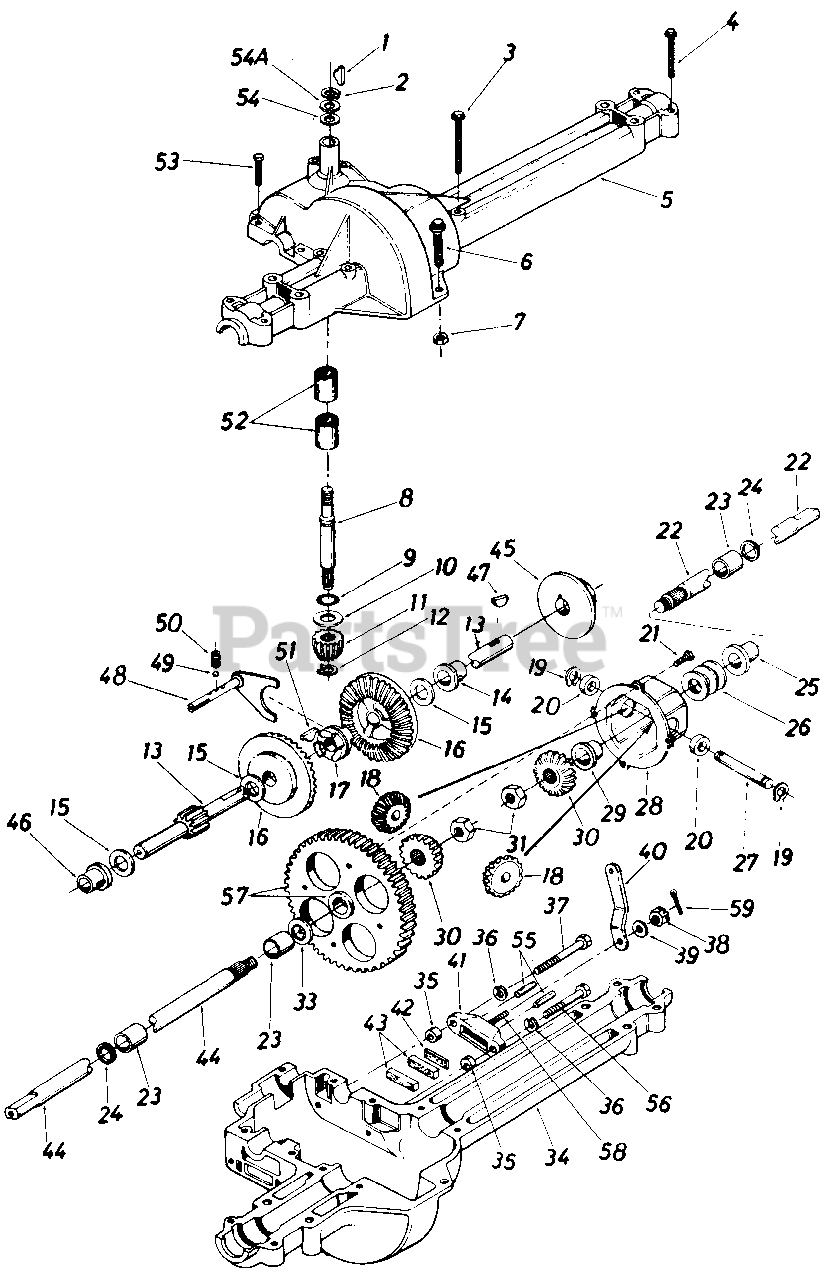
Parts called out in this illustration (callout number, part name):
1	#4 Hi-Pro Key 3/32 x 5/8" Dia.
2	Snap Ring .625" Shaft
3	Hex Bolt 1/4-20 x 1.75" Lg.
4	Hex Bolt 1/4-20 x 1.25" Lg.
5	Upper Housing
6	Hex Fl-Bolt 1/4-20 x .75" Lg.
7	Hex Nut 1/4-20 Thd.
8	Input Shaft
9	Square Seal 5/8" I.D.
10	Thrust Washer 5/8" I.D. x 1.25" O.D.
11	Pinion Input 14T
12	Retaining Ring 7/16" Ext.
13	Drive Shaft R.H.
14	Flange Brg. 5/8" I.D. x 3/4" Lg.
15	Fl-Wash.
16	Bevel Gear 42T
17	Clutch Collar
18	Miter Gear 15T
19	Snap Ring
20	Thrust Bearing 1/2" I.D. x 1.0" O.D.
21	Pan Head Scr. 1/4-20 x .50" Lg. w/Patch
22	Axle R.H.
23	Sleeve Bearing 3/4" I.D. x 1.0" Lg.
24	Oil Seal 3/4" I.D.
25	Flange Bearing 3/4" I.D. x 15/16" Lg.
26	Fl-Wash. .760" I.D. x 1.49" O.D.
27	Cross Shaft
28	Differential Housing Ass'y.
30	Miter Gear
31	Hex Ins. L-Nut 1/2-20 Thd.
33	Fl-Wash. .75" I.D. x 1.5" O.D.
34	Lower Housing
35	Spacer .53" O.D. x 3/8a Lg.
36	L-Wash. 1/4" I.D.
37	Hex Bolt 1/4-20 x 1.50" Lg. (Grade 5)
38	Castle Nut 5/16-24 Thd.
39	Fl-Wash. .34" I.D. x .875" O.D.
40	Actuating Arm R.H.
41	Brake Yoke
42	Puck Plate
43	Brake Puck
44	Axle L.H.
45	Brake Disc
46	Flange Bearing 5/8" I.D. x 15/16" Lg.
47	Woodruff Key 3/16 x 5/8 HT
48	Shift Fork Ass'y.
49	Ball Detent .250" Dia.
50	Spring Detent
51	#9 Hi-Pro Key 3/16 x 3/4" Dia. HT
52	Needle Brg. 5/8" I.D. x 1/2" Lg.
53	Hex Bolt 1/4-20 x 1.00" Lg.
54	Fl-Wash. 5/8" I.D. x .030
54A	Fl-Wash. 5/8" I.D. x .040
55	Actuating Pin 5/16" Dia.
56	Hex Bolt 1/4-20 x 1.50" Lg. (Grade 5)
57	Differential Gear 72T Ass'y. w/Bearing
58	Sq. Hd. Bolt 5/16-24 Thd.
59	Cotter Pin 3/32" Dia. x .50 Lg.
